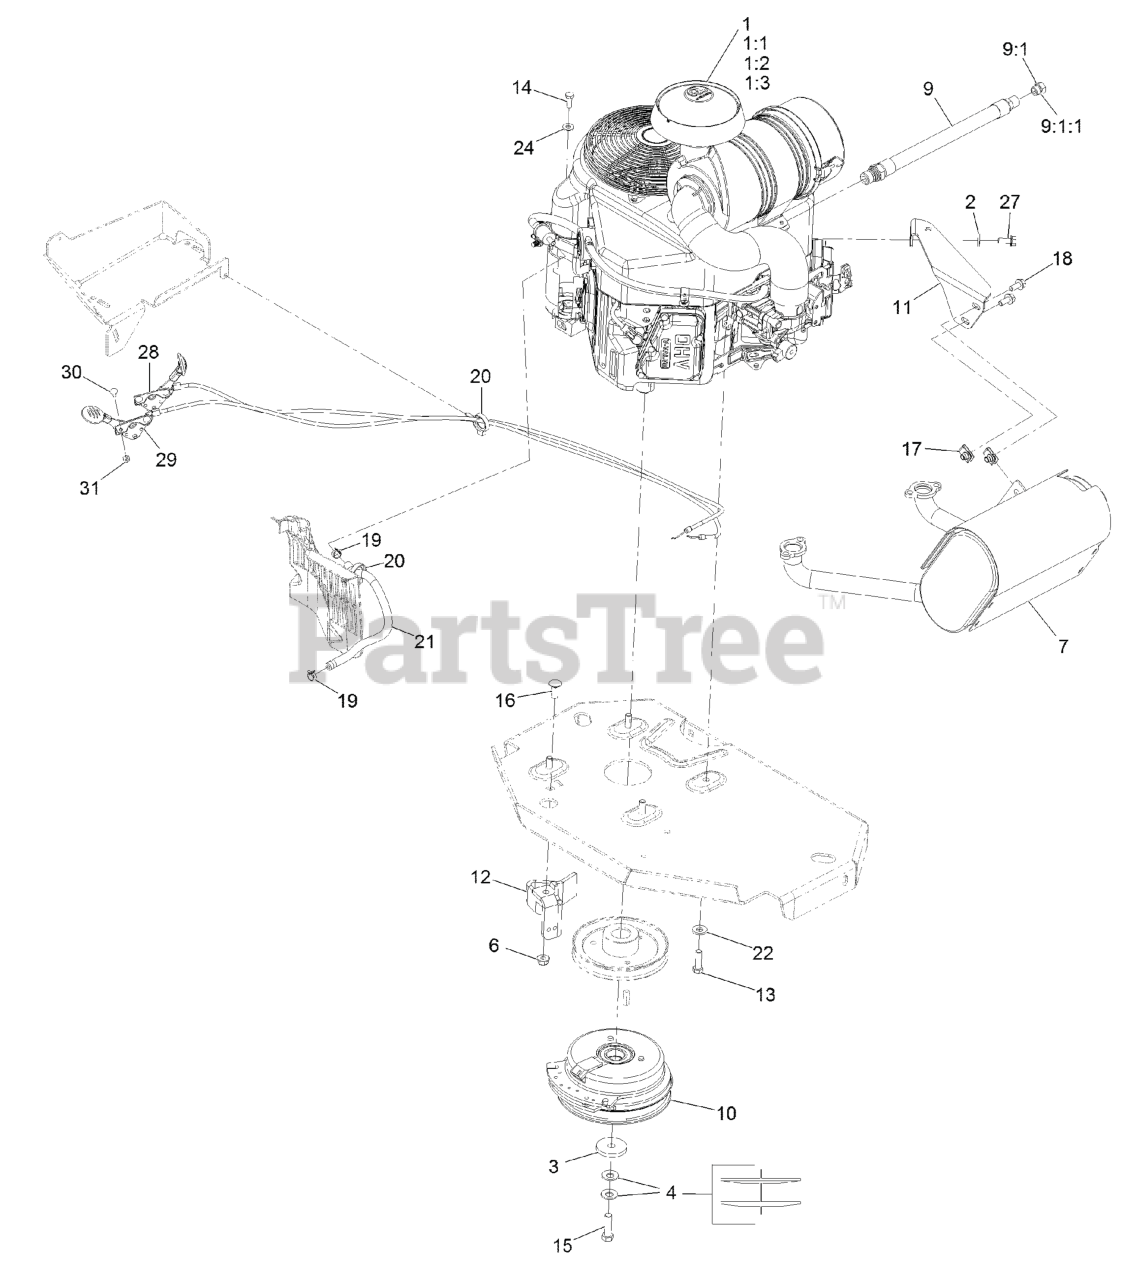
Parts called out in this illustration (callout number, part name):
1:1	Kawasaki 49065-7007 Engine Oil Filter
1:2	Kawasaki 11013-7044 Engine Air Filter
1:3	Kawasaki 11013-7045 Safety Filter
2	WASHER-SPRING
3	WASHER-CLUTCH
4	WASHER-SPRING
6	NUT-HF, NI
7	MUFFLER
9	ENGINE OIL DRAIN HOSE ASM
9:1	PLUG-HH
9:1:1	O-RING
11	BRACKET-MUFFLER
12	CLUTCH-ANCHOR
13	SCREW-HH
14	SCREW-HH
15	SCREW-HH 7/16-20 X 1 1/2 W/LOCTITE
16	SCREW-CARR
18	SCREW-HHF
19	CLAMP-HOSE
20	CLAMP-HOSE
21	HOSE-FUEL
22	WASHER-BELLEVILLE
24	WASHER-PLAIN
27	SCREW-HHF
28	ASM, CHOKE CABLE
29	ASM,THROTTLE CABLE
30	BOLT-CARR
31	NUT-LOCK, NI
